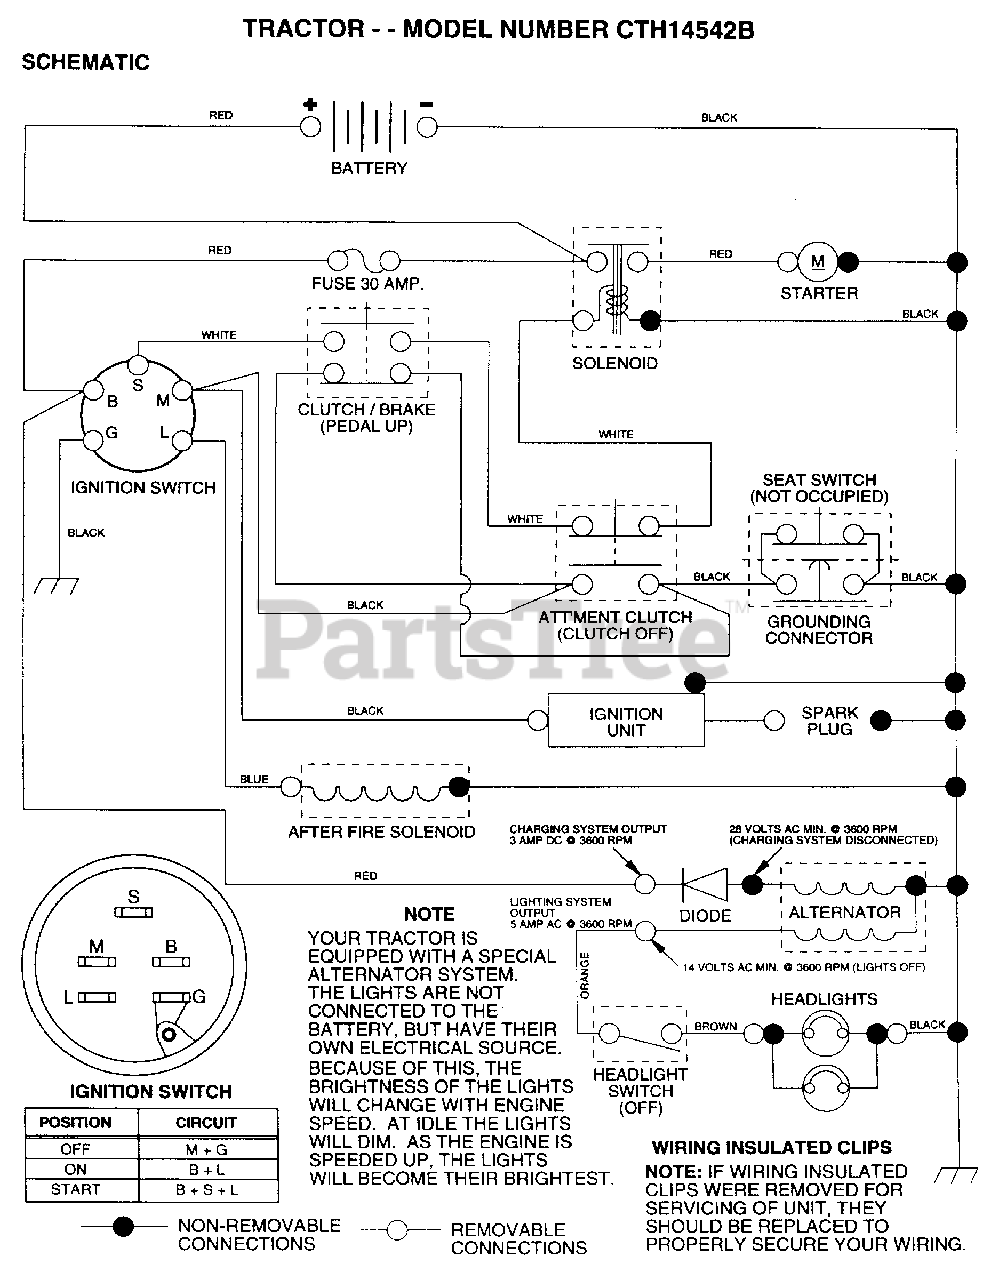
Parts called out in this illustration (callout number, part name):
2	BOLT LT
3	WASHER
4	LOCKWASHER
7	TUBE T
9	HOSE CLAMP T
15	FASTNER.SNAP-IN
20	NUT
21	"HARNESS,LIGHT SOC"
22	HEADLAMP BULB
24	CABLE.BTRY.6GA.RD
25	CABLE.BTRY.6GA.38
26	FUSE HYT
28	CABLE T
29	SWITCH SEAT
32	COVER KEY SWITCH
33	KEY MLD GEN DELTA
34	SWITCH LT
35	BRACKET LT
36	SCREW
38	BRACKET SWITCH IN
39	SWITCH INTERLOCKT
40	HARNESS.IGN.DASH.
41	BOLT HXHD FIN
44	NUT HXKEP 1/4X20
48	ADAPTER AMMETER
49	LOCKWASHER
70	HARNESS.ENG.DUAL
